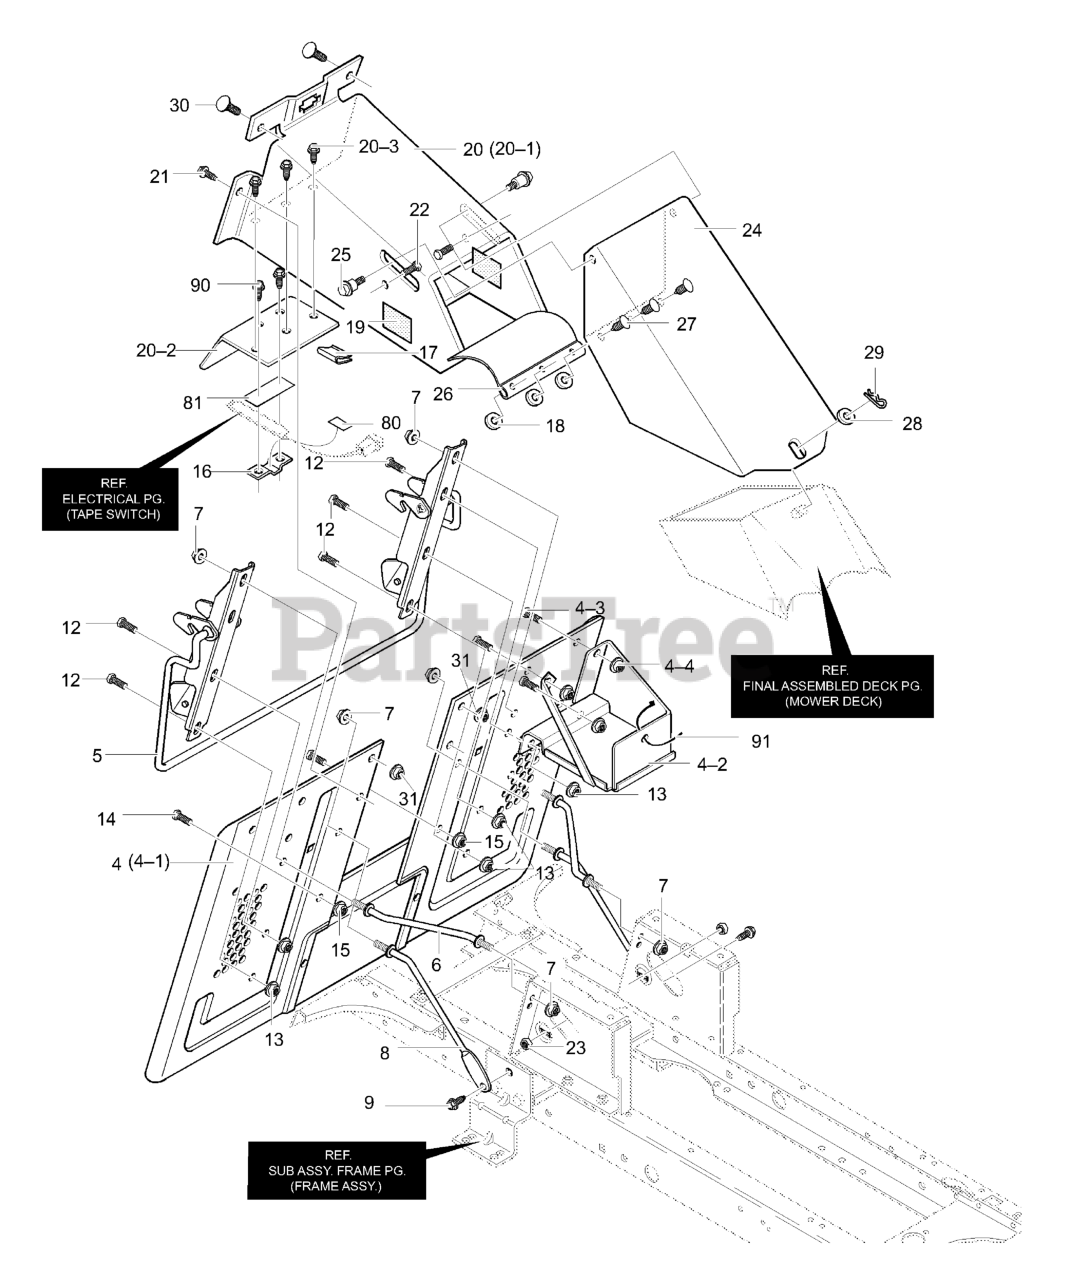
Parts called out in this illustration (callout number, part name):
4	Assy., Back Plate/Battery
4-1	Assy. Back Plate Flat
4-2	Battery Tray Assembly
4-3	Screw, 5/16-18 x 0.50
4-4	Nut, 5/16-18 Hexwdfllk Whiz
5	Weldment - Latch Lever
6	Rod, Brace
7	Nut, 3/8-16 Hwdfl Whiz-lock
8	Rod, Brace
9	Screw, 5/16-18 x 0.75
12	Screw, 5/16-18 x 0.75
13	Nut, 5/16-18 Hexwdfllk Whiz
14	Screw, 5/16-18 x 0.75
15	Nut, 5/16-18 Hexwdfllk Whiz
16	Bracket, Flex Switch Mounting
17	Wire Clip, Adhesive
18	Flatwasher
19	Pad, Adhesive
20	Asm., T/A Shield & Upper Chute
20-1	Chute Weld Asm. Upper
20-2	Shield, Transaxle
20-3	Screw, 1/4-20x.63
21	Screw, 5/16-18 x 0.75
22	Bolt, Carriage 5/16-18x.75
23	Nut, 5/16-18
24	Middle Chute Assembly
25	Shoulder Bolt
26	Flap, Chute
27	Fastener, Ratchet
28	Flatwasher
29	Pin, Hair
30	Bolt, Carriage 5/16-18x.75
31	Nut, 5/16-18
80	Tape, Double Sided Foam 3/4"
81	Tape, Double Sided Foam 3/4"
90	Screw, 1/4-20x.63
91	Cable Tie
